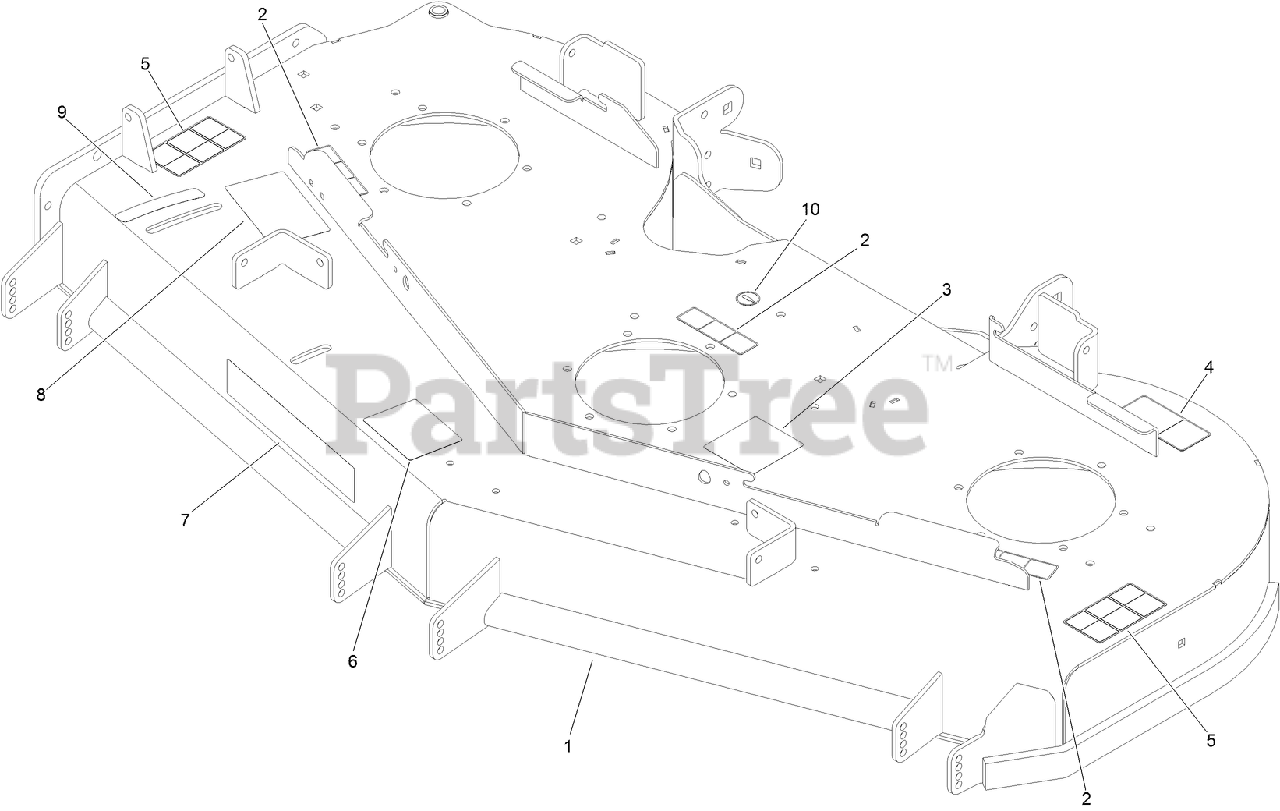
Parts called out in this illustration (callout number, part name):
1	DECK DECAL ASM
2	DECAL-COVER, MISSING
3	DECAL-ROUTING, DECK BELT
4	DECAL-TORQUE, BLADE BOLT
5	DECAL-DANGER
6	DECAL-SCALP, ANTI
8	DECAL-ADJUSTMENT, BAFFLE
9	DECAL-SETTING, BAFFLE
10	DECAL-GREASE
